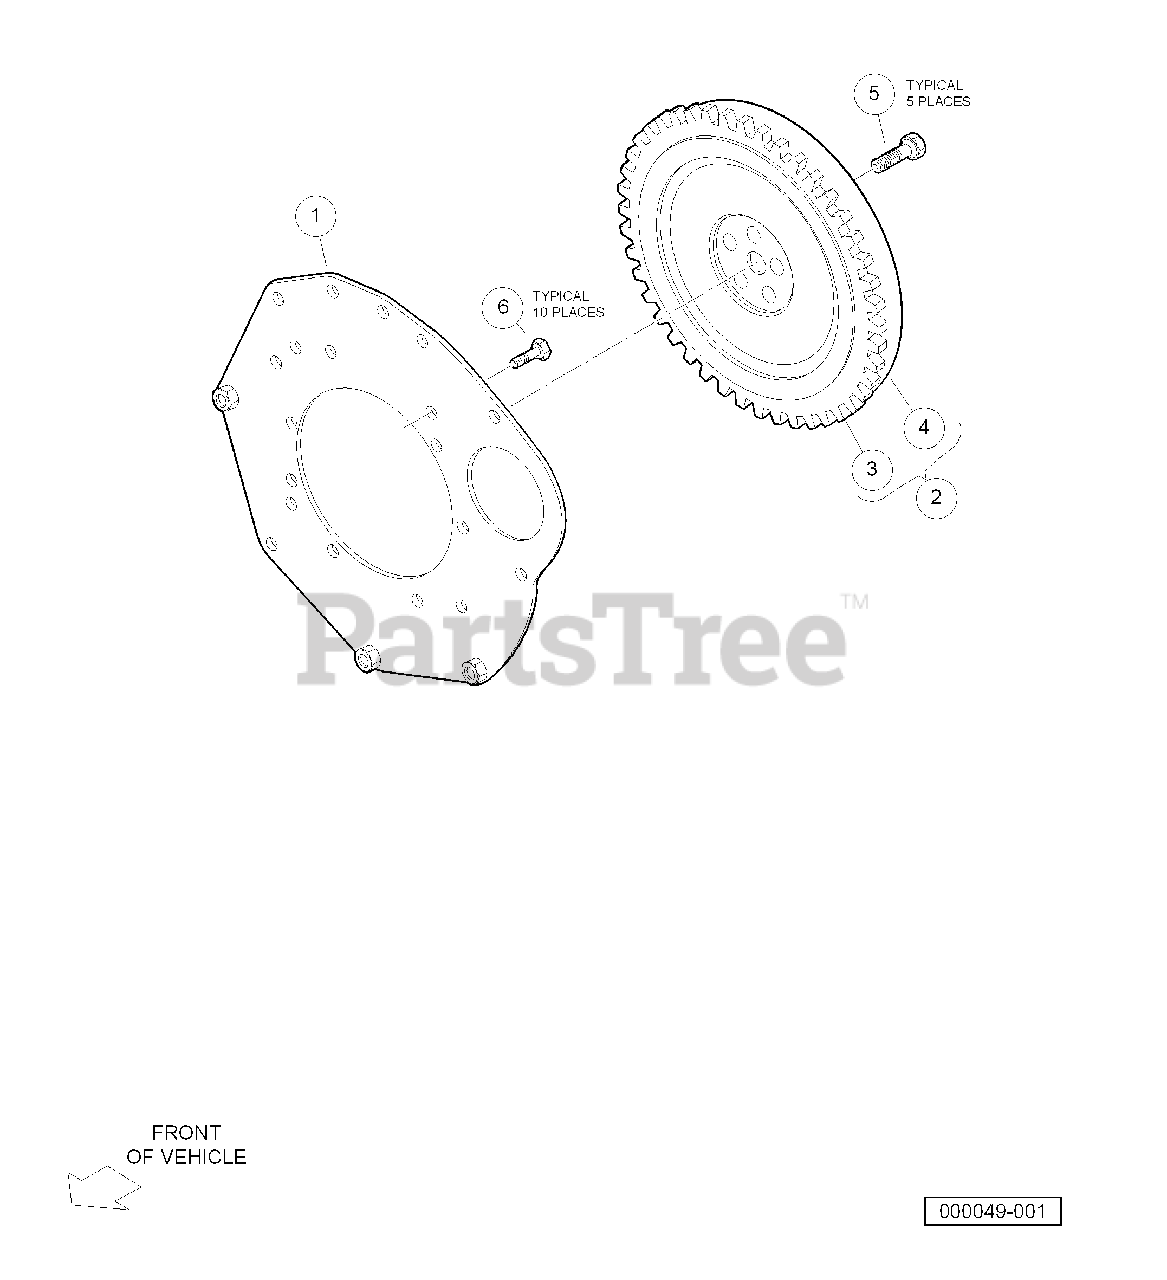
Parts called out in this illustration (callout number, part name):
1	Plate, Rear End
2	Flywheel
3	GGar, Ring, D722
4	Flywheel
5	Bolt, Flange Head, M10 X 1.5 X 25
6	Bolt, End Plate
